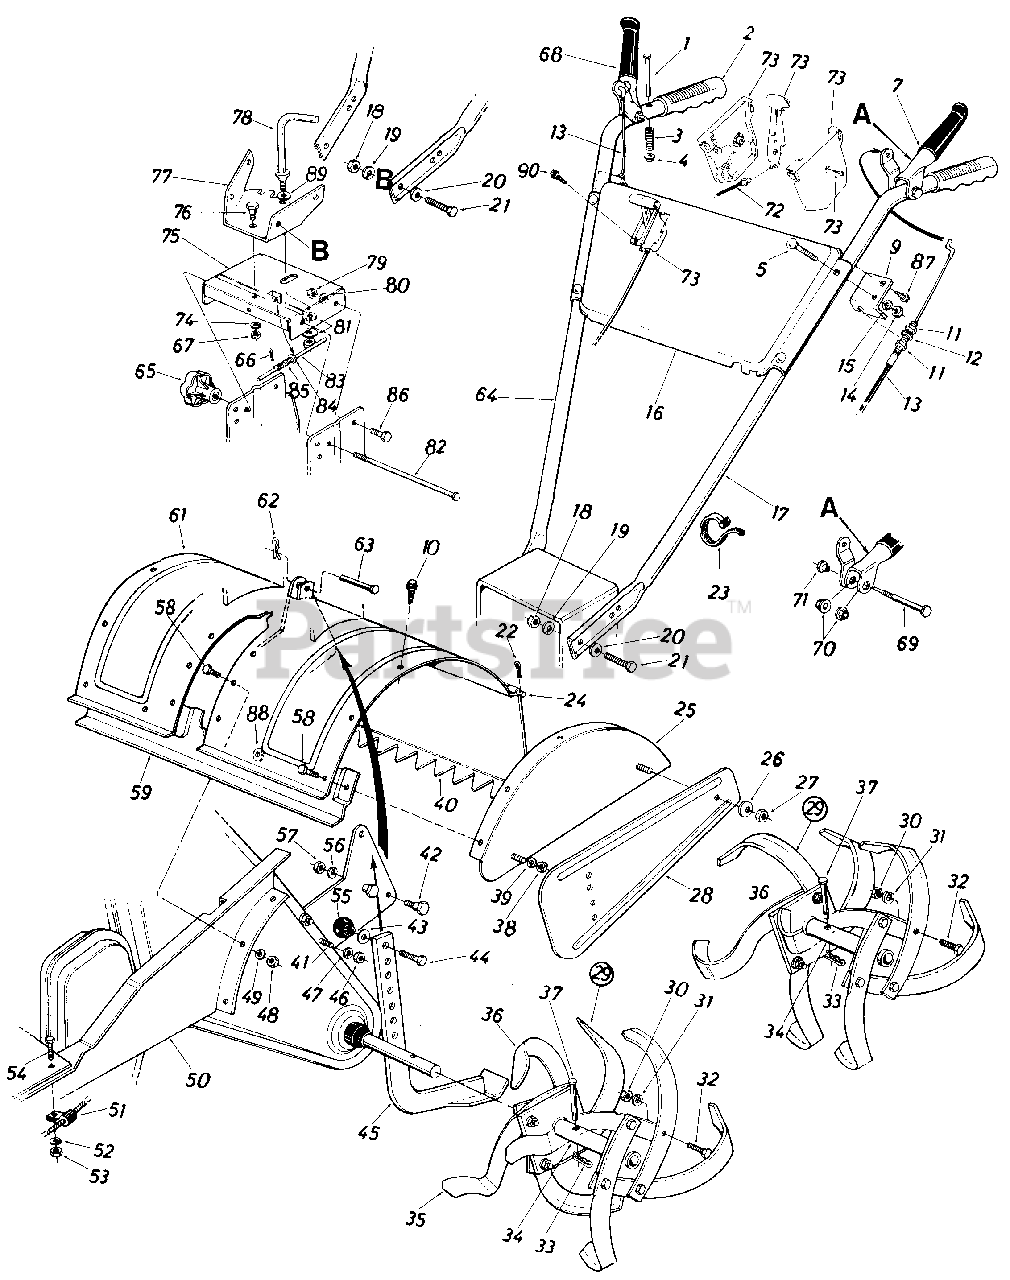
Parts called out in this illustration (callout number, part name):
1	Clevis Pin 1/4 Dia. x 2.25"
2	Grip
3	Compression Spring .33" O.D. x 1.2" Lg.
4	Cap Speed Nut 1/4" Rod
5	Carr. Bolt 5/16-18 x 1.75"
7	Clutch Grip Ass'y.-L.H.
9	Clutch Cable Bracket
10	Hex Wash. S-Tap Scr. 5/16-18 x .62" Lg.
11	Hex Nut 5/16-24 Thd.
12	L-Wash. 5/16" I.D.
13	Clutch Control Cable
14	Hex Nut 5/16-18 Thd."
15	L-Wash. 5/16" I.D.
16	Handle Panel
17	Handle-L.H.
18	Hex Nut 3/8-16 Thd.
19	L-Wash. 3/8" I.D.
20	Bell-Wash. 3/8" I.D.
21	Hex Bolt 3/8-16 x 1.00" Lg.
22	Cotter Pin 3/32" Dia. x 3/4"
23	Cable Tie
24	Tiller Flap Rod
27	Hex Nut 5/16-18 Thd.
30	Hex Nut 3/8-24 Thd.
31	L-Wash. 3/8" I.D.
32	Hex Bolt 3/8-24 x 1.25" Lg.
33	Hairpin Cotter
38	Hex Nut 5/16-18 Thd.*
39	L-Wash. 5/16" I.D.
41	Hex Bolt 5/16-18 x 1.0" Lg.
42	Shld. Bolt 1/2" Dia. x .426"
43	Fl-Wash. 3/8" I.D. x 5/8" O.D.
44	Hex Bolt 3/8-16 x 3/4" Lg.
46	Hex Nut 5/16-18 Thd.
47	L-Wash. 5/16" I.D.
48	Hex Nut 5/16-18 Thd.
49	L-Wash. 5/16" I.D.
52	L-Wash. 5/16" I.D.
53	Hex Nut 5/16-18 Thd.
54	Hex Bolt 5/16-18 x 3/4" Lg.
55	Ball Knob 11/4" Dia.
56	L-Wash. 3/8" I.D.*
57	Hex Nut 3/8-16 Thd.
58	Hex Bolt 5/16-18 x .75" Lg.
62	Hairpin Cotter
63	Clevis Pin 3/8" Dia.
64	Handle-R.H.
66	Cotter Pin 1/16" Dia. x .75" Lg.
67	Hex Cent. L-Nut 3/8-16 Thd.
68	Clutch Grip Ass'y.-R.H.
69	Shoulder Bolt .38" Dia. x 1.53" Lg.
70	Hex Flange Plastic Bearing
71	Shoulder Nut 1/4-20 Thd.
72	Throttle Control Wire
73	Throttle Control Box Ass'y.
74	Bell-Wash. .40" I.D. x 1.13" O.D.
79	Hex Cent. L-Nut 3/8-16 Thd.
80	Bell-Wash. .40" I.D. x .88" O.D.
81	Bell-Wash. 1/2" I.D. x 1.00" O.D.
82	Lock Pin 5/16" Dia. x 8"
83	Lower Sliding Ass'y.
84	Fl-Wash. .291" I.D. x .62" O.D.
85	Compression Spring .36" O.D. x 1.00" Lg.
86	Shoulder Bolt 1/2" Dia. x .170" Lg.
87	Hex Wash. S-Tap Scr. 1/4-20 x.50" Lg.
88	Bell-Wash. 5/16" I.D.
89	Fl-Wash. 5/8" I.D.
90	Self-Tap Scr. #10 x 1/2" Lg.
